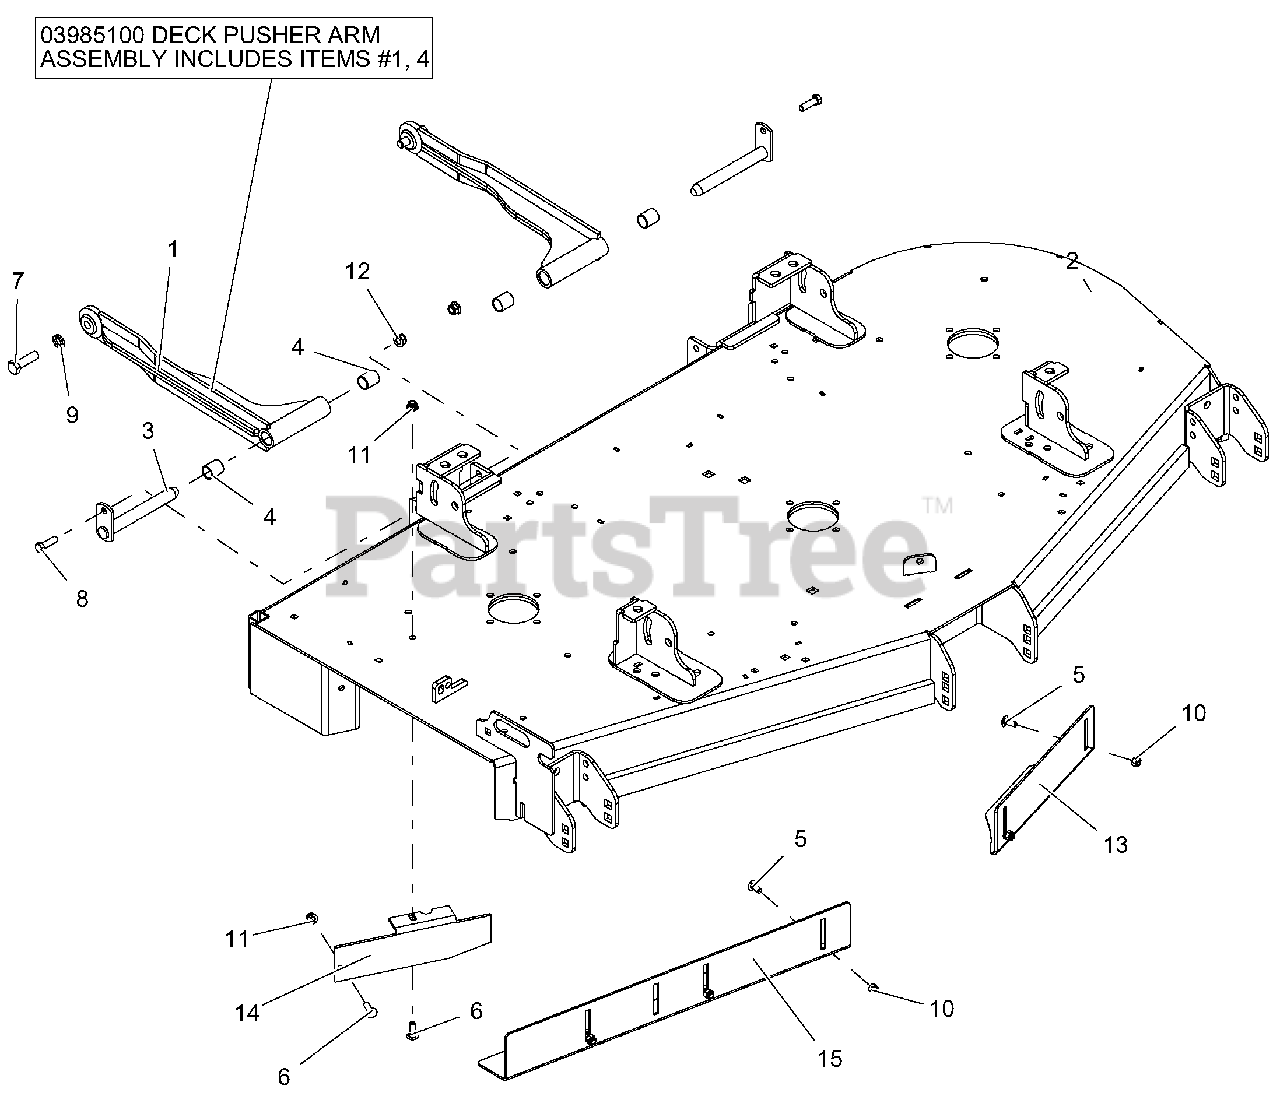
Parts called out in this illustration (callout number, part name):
1	WMT, DECK STABILIZER ARM-BLACK
2	WLDMT, 60" SIDE DISCH DECK
3	WLDMT, MOWER MTG. PIN
4	BRG, .75 X .875 X 1.00
5	BLT-RDHDSQNK .31-18X.75 G5 YWZC
6	BLT-RDHDSQSHNK .31-18X1.00 G5 Y
7	BLT-HEX .50-13X1.75 GR5 YWZC EP80
8	BLT-HEX .38-16X1.25 GR5 YWZC
9	WSHR-LK .50X.125 REG YWZC
10	NUT-LK-NYL .312-18 YWZC
11	NUT-LK-NYL-FLG .31-18 YWZC
12	NUT-LK-NYL-FLG .38-16 YWZC
13	BAFFLE, 60" LH VACUUM
14	BAFFLE, 60" DISCHARGE
15	BAFFLE, 60" RH VACUUM
